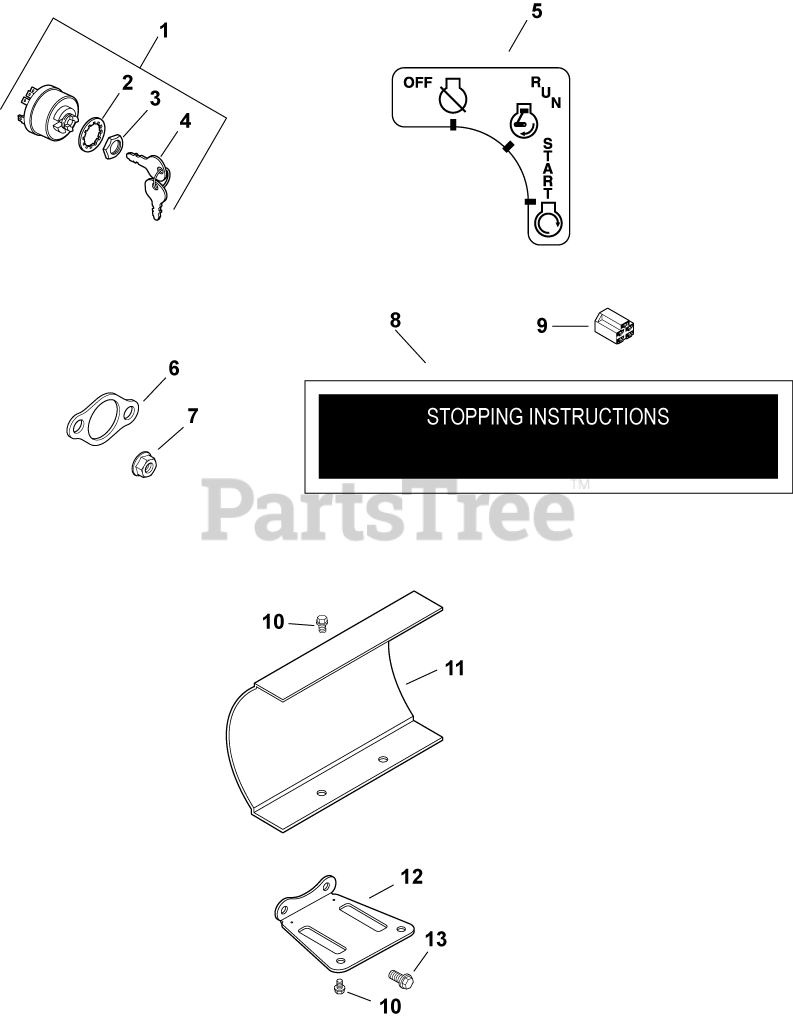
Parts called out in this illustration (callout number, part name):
1	SWITCH ASSY, KEY (KM)-USE 25 099 32-S
2	WASHER, INTERNAL TOOTH
3	NUT, KEY SWITCH
4	KEY, SET -USE 48 340 01-S
5	DECAL, KEY SWITCH
6	GASKET, EXHAUST
7	NUT, FLG M8X1.25
8	DECAL, STOPPING INSTRUCTION
9	CONNECTOR
10	SCREW, FLG M6X1.0X12
11	SHIELD, HEAT-USE 24 314 50-S
12	BRACKET, MUFFLER
13	SCREW, FLG M8X1.25X20
